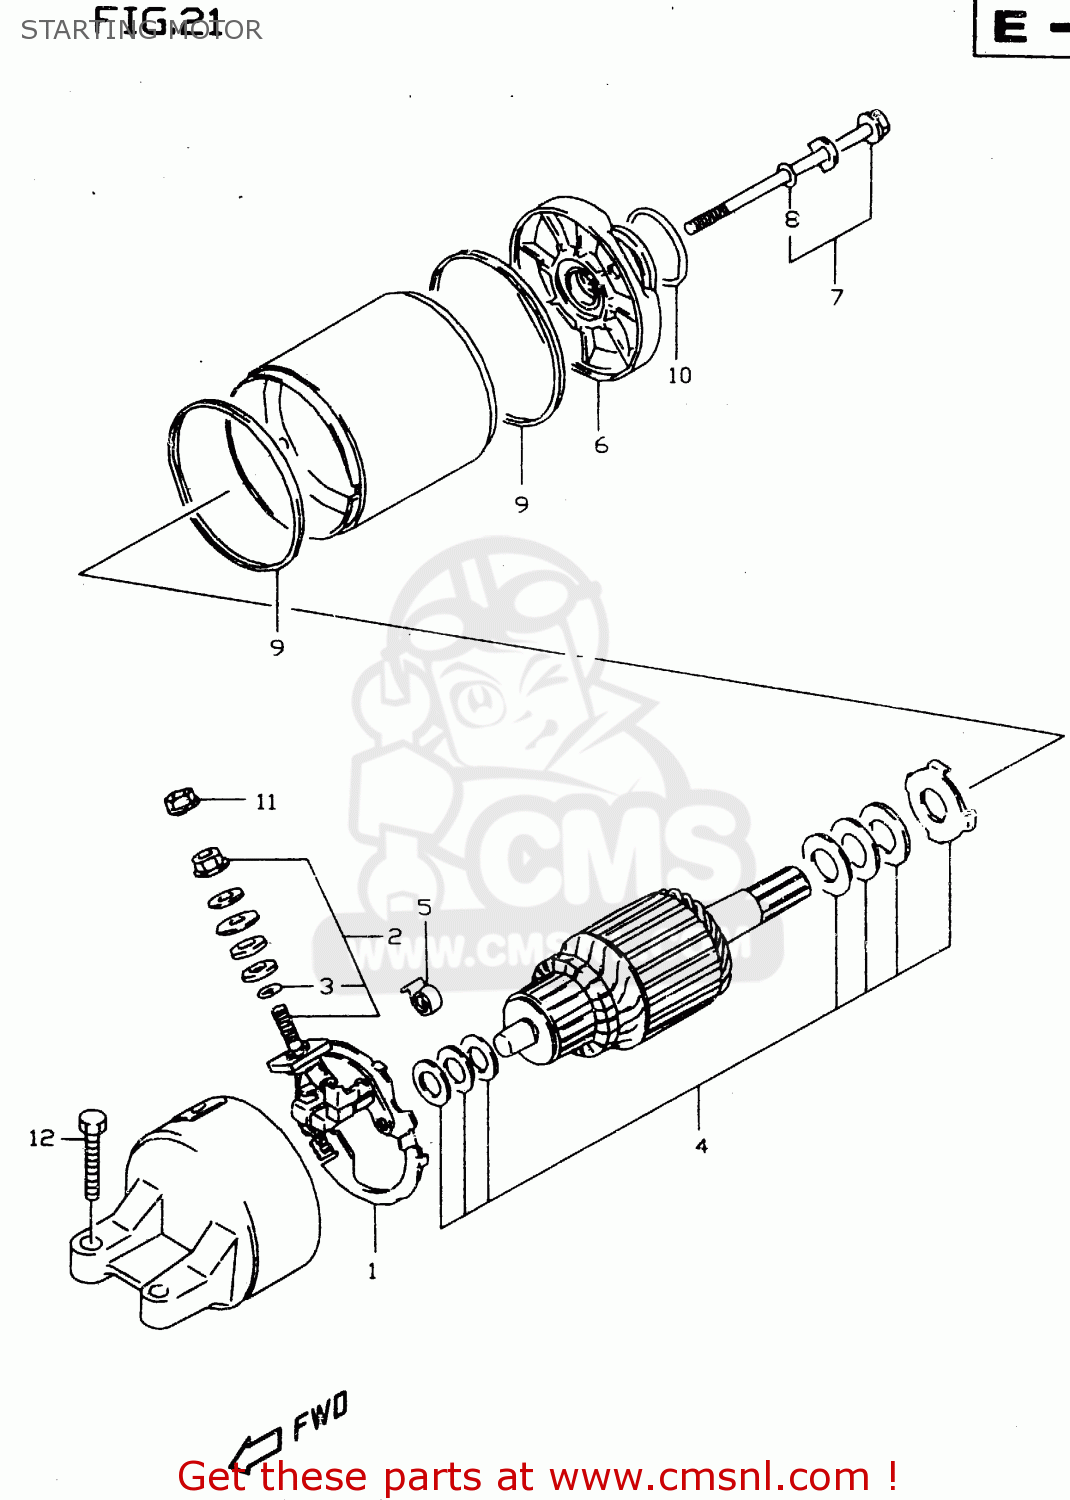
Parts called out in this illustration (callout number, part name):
1	HOLDER SET,BRUSH
2	TERMINAL SET,BRUSH,PLUS
3	O RING
4	SHIM SET,STARTING MOTOR
5	SPRING,BRUSH
6	BRACKET ASSY,FR
7	BOLT SET,STARTING MOTOR
8	O RING
9	SQUARE RING
10	O RING(D:3,ID:24.5)
11	NUT
12	SCREW (6X25)
